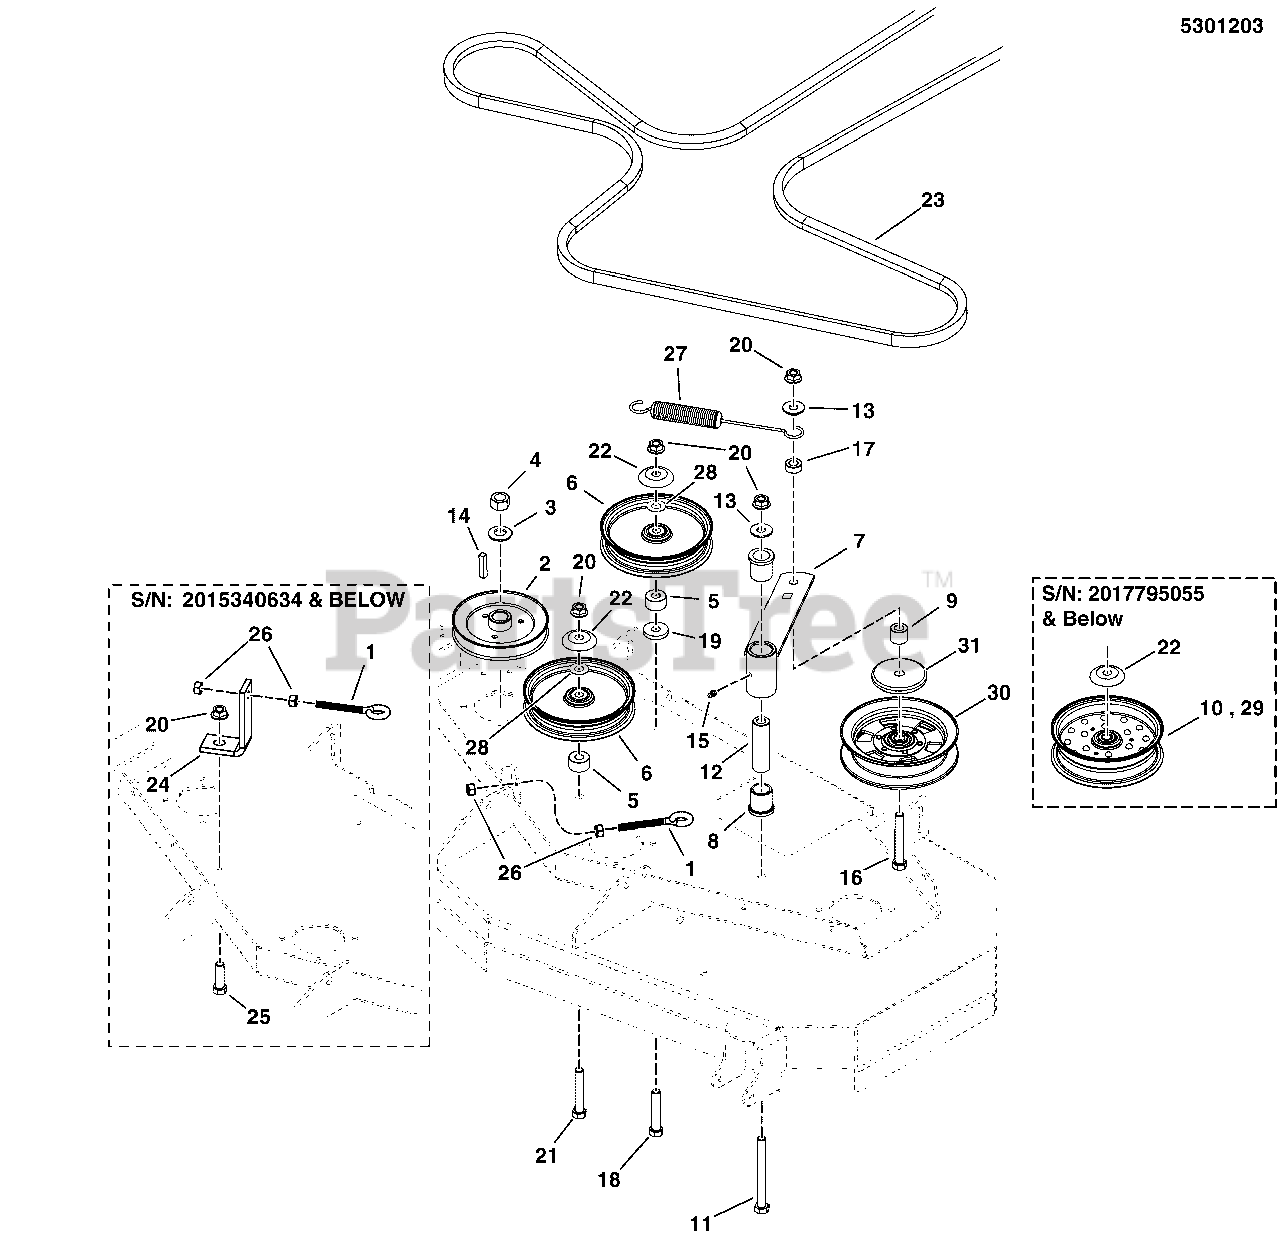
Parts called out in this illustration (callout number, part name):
1	EYE BOLT, 3/8-16 X 4, 2.13THRD, 1 EYE,CZ
2	PULLEY, 5.540OB X 3985ID, SINGLE B-SEC (48" Deck, S/N: 534 & above)
3	WASHER, 3/4" Belleville (Included with Complete Spindle Assembly)
4	NUT, 3/4-16 Hex (Included with Complete Spindle Assembly)
5	SPACER, .52 X 1.25 X .70, PM, CZ
6	*PULLEY, FLAT IDLER, 6-3/4"
7	ASSM, IDLER ARM - BLK - 5407039A (SV)
8	BUSHING, FLANGE
9	SPACER, .52 X 1.00 X .88, PM, CZ
10	PULLEY, IDLER, 6.75 OD X 1.62 FACE
11	BOLT, 1/2-13 X 5" GD5 YZ
12	SPACER, .52 X 1.00 X 3.50
13	WASHER, 1/2" USS
14	KEY, 1/4 SQ. X 1-1/4
15	GREASE FITTING, 1/4-28 STRAIGHT
16	CAPSCREW, Hex Hd, 1/2-13 x 3-1/2
17	SPACER, .52 X 1.00 X .44, CZ
18	BOLT, 1/2-13 X 2-3/4 GD5 YZ
19	WASHER, .53 X 1.50 X .25
20	NUT, Hex Flange, 1/2-13
21	BOLT, 1/2-13 X 2-1/2 GD5 YZ
22	SHIELD, PULLEY BEARING, CZ
23	BELT, 5V, 145.40"EL, LRG ARAMID, WRP, RC
24	BRACKET, EYEBOLT MOUNT - BLK
25	BOLT, 1/2-13 X 1-1/2 GD5 YZ
26	NUT, Hex, 5/16-18
27	SPRING-EXT, 1.04 ODX10.535LGX.148WR, BLK
28	WASHER, 1/2
30	PULLEY,IDLER,BACKSIDE,NOSEAM 6.25ODX.5ID
31	SHIELD, BEARING, 1/2ID X 2-7/8 OD, CZ
